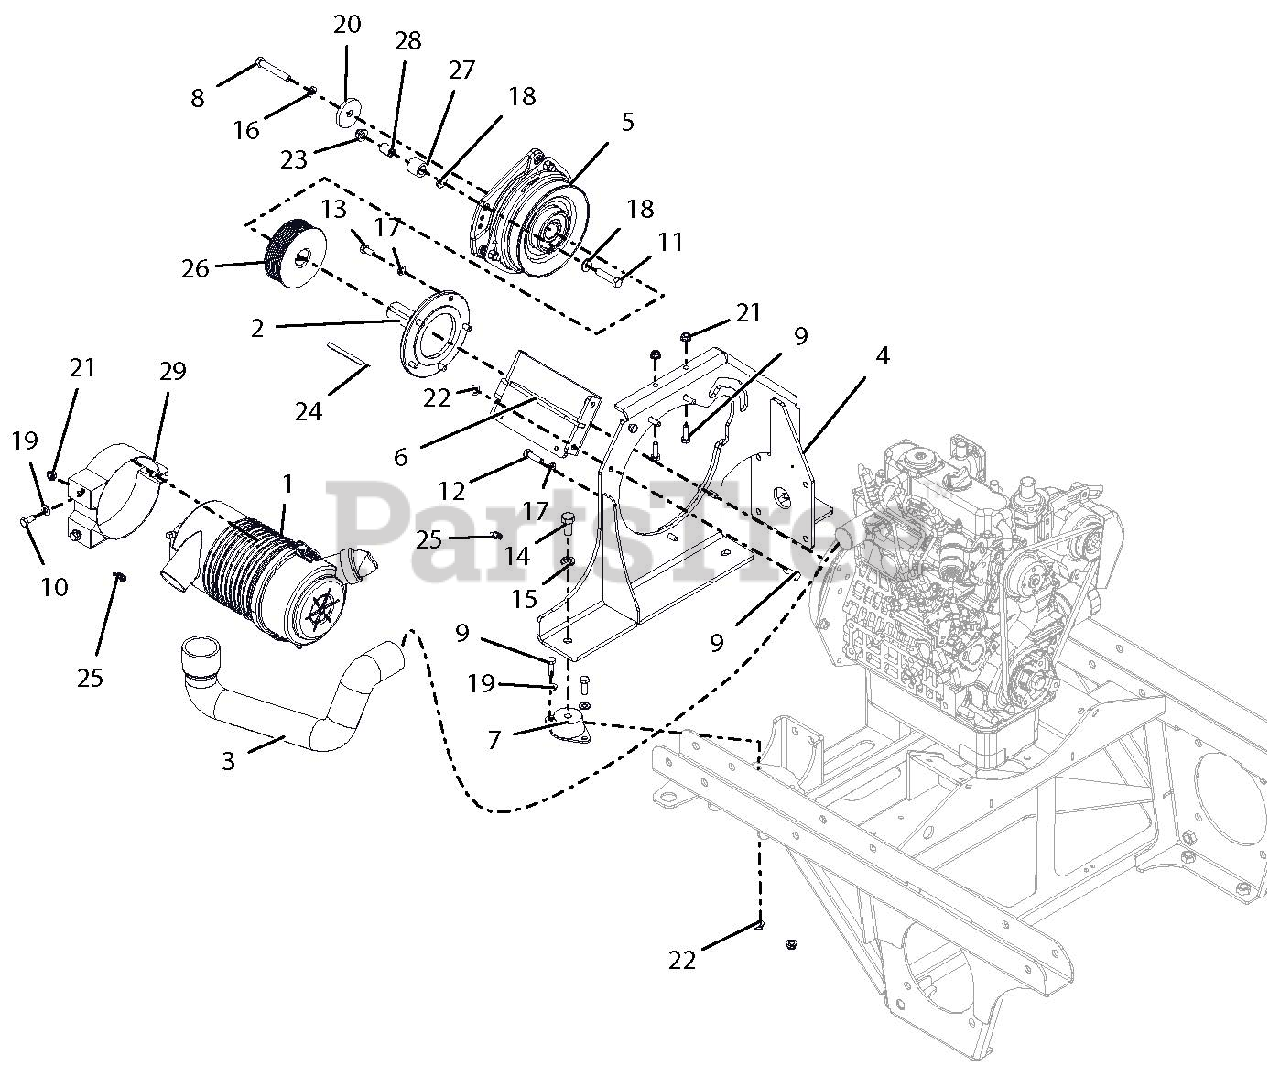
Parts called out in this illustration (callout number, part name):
1	CLEANER, AIR
2	STUB SHAFT, KUBOTA DIESEL
3	HOSE, AIR CLEANER OUTLET
4	WDMT, DIESEL ENGINE MOUNT
5	CLUTCH, DIESEL REVERSE MOUNT
6	WDMT, CLUTCH STOP-DIESEL
7	MOUNT, ENGINE, VIBRATION ISO
8	BLT-HEX .38-24X2.5 GR5 YZ EP80
9	@BLT-HEX .31-18X1.00 GR5 YWZC
10	@BLT-HEX .31-18X.75 GR5 YWZC
11	@BLT-HEX .38-16X1.75 GR5 YWZC
12	@BLT-HEX M8 X 1.25X30 GR5 YWZC
13	@BLT-HEX M8-1.25X20 YWZC
14	BLT-HEX .50-20X1.00 GR5 YWZC
15	@WSHR-LK .50X.125 REG YWZC
16	@WSHR-LK .38X.094 REG YWZC
17	WSHR-LK M8 YWZC
18	@WSHR-FL-STL.38X.875X.083 YWZC
19	@WSHR-FL-STL.344X.688X.065YWZC
20	WSHR-FL-STL .469X2.00X.25 YWZC
21	@NUT-SPNLK-FLG .312-18 YWZC
22	@NUT-LK-NYL-FLG .31-18 YWZC
23	@NUT-LK-NYL-FLG .38-16 YWZC
24	KEY-SQ. .25X3.50X.25 SAE
25	CLAMP, HOSE #32 (1.56"-2.50")
26	SHEAVE, PVK 8-RIB 4.125 DIA.
27	BUMPER,RUBBER .62X1.0X.88 LG
28	BUSH.,S.407X.625X.813 ST
29	BRACKET, AIR CLEANER MOUNT
